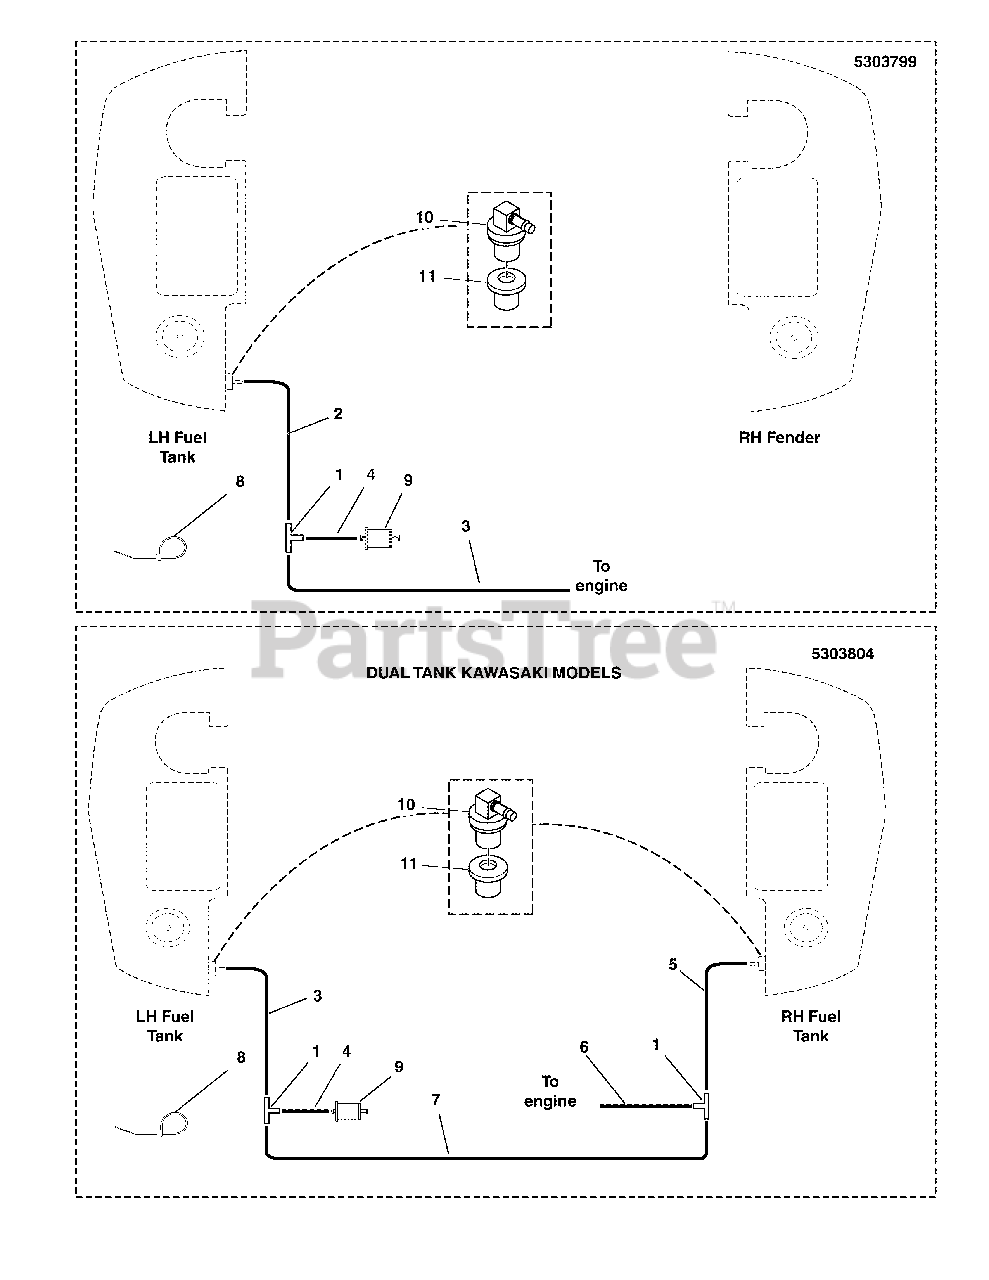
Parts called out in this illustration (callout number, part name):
1	FITTING, 3/16" TEE, BARB TYPE, HDPE
2	HOSE, VAPOR, 5MM ID, 30.00 LG
3	HOSE, Vapor, 5 MM ID X 9 MM OD X 12"
4	HOSE, VAPOR, 5MM ID, 2.00 LG
5	HOSE, Vapor, 5 MM ID, 26.00 LG
6	HOSE, VAPOR, 5MM ID, 18.00 LG
7	HOSE, VAPOR, 5MM ID, 10.50 LG
8	TIE,SELF-LOCKING, 6"
9	FILTER, Fuel
10	REMOTE VENT ASSEMBLY
11	GROMMET
